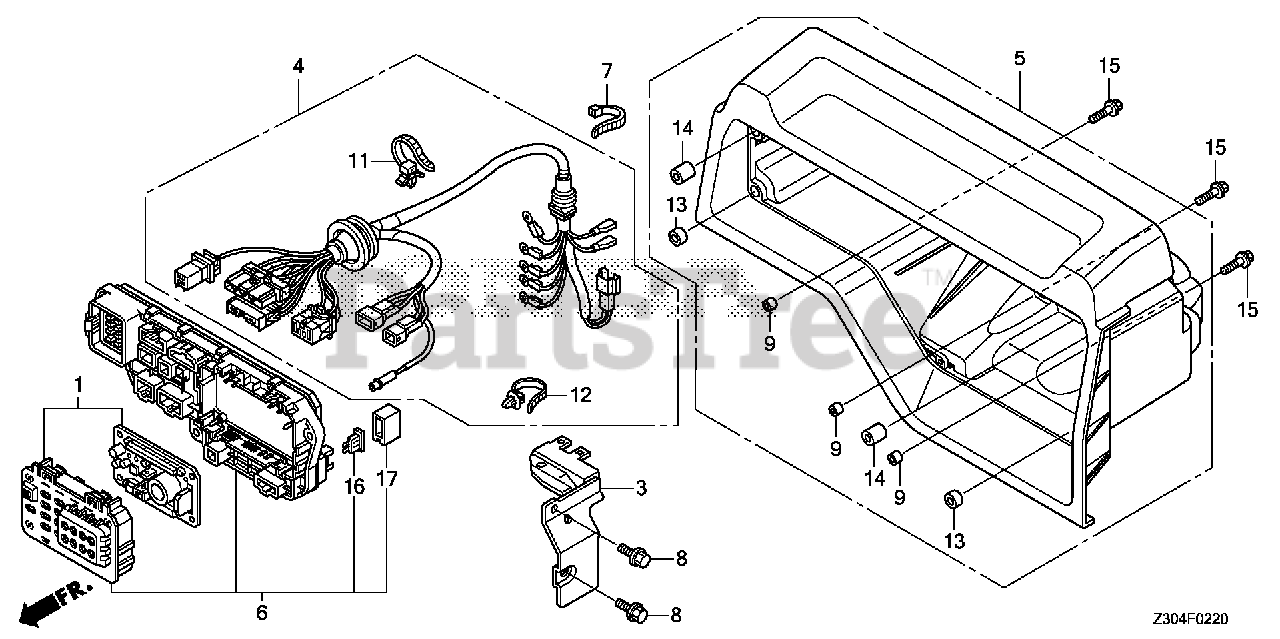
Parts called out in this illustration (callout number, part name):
1	COVER ASSY., AUTOMATIC VOLTAGE REGULATOR
3	BASE, HARNESS CLIP
4	WIRE HARNESS ASSY., GENERATOR
5	CASE, CONTROL PANEL *NH314* (CONDUCT GRAY)
6	BOX ASSY., JUNCTION
7	TIE, CABLE (C)
8	BOLT, FLANGE (6X12) (CT200)
9	COLLAR, BODY COVER
11	CABLE, STRAP
12	CLIP, HARNESS BAND (145MM) (BLACK)
13	COLLAR, CONTROL CASE
14	COLLAR, CONTROL CASE
15	BOLT, FLANGE (6X20)
16	FUSE, BLADE (10A)
17	COVER, FUSE
